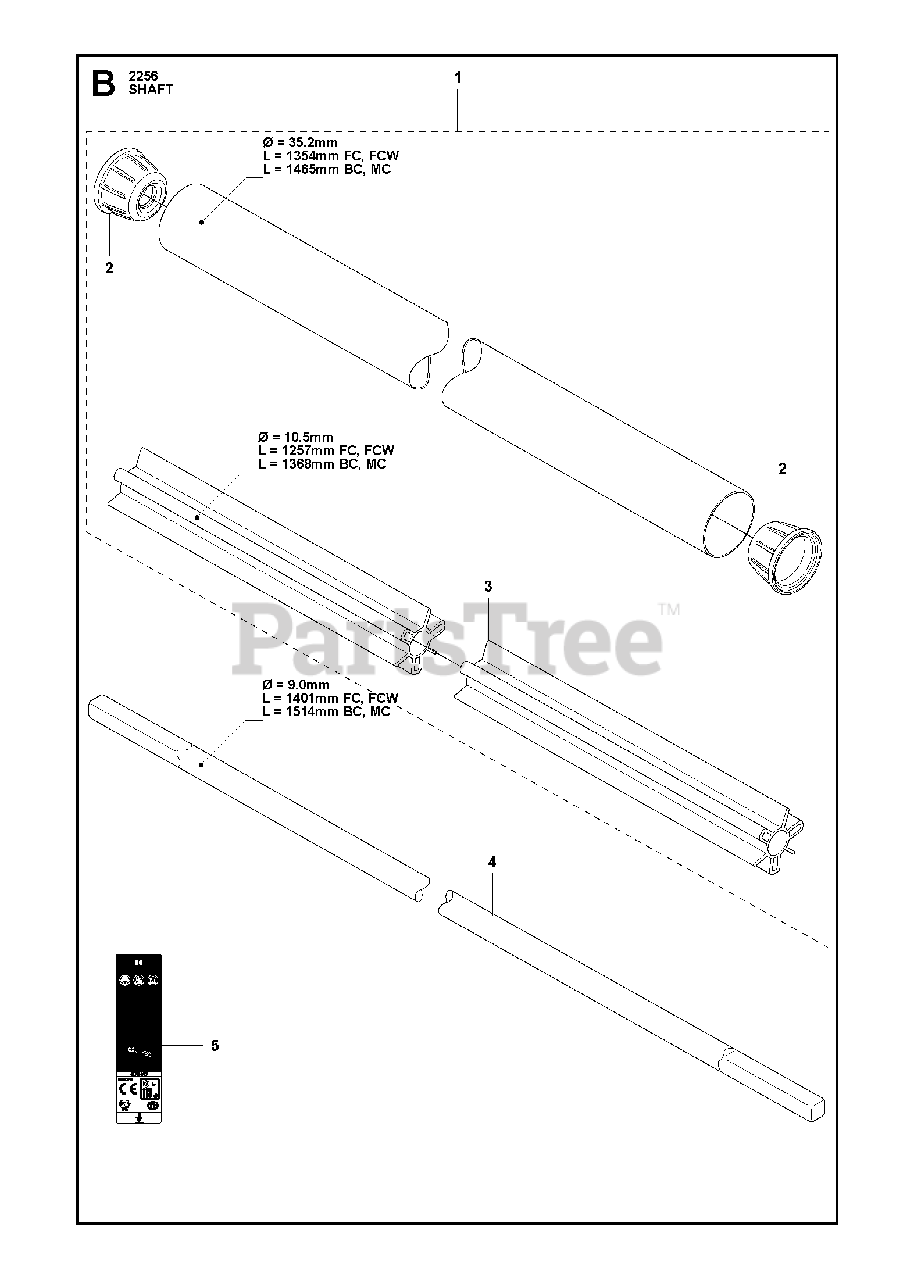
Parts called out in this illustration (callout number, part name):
1	TUBE ASSY
2	RP SPACER
3	BEARING SHAFT
4	DRIVE SHAFT
